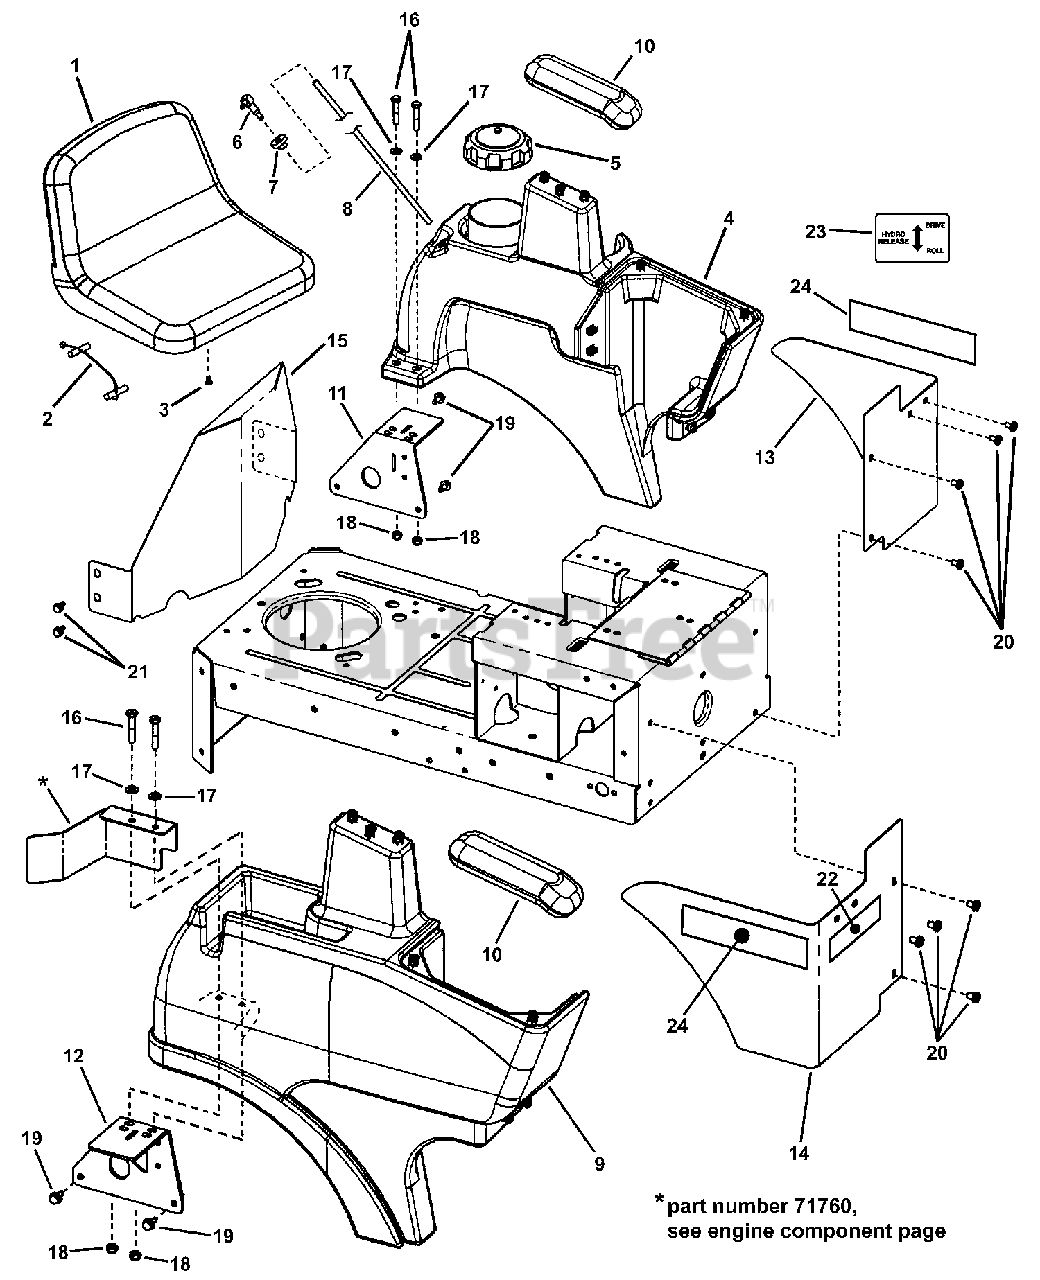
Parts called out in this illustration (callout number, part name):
1	SEAT, Milsco High Back
2	TETHER, Seat
3	SCREW, 1/4-20 x 5/8" Pan Head Self-Tap (Torx)
4	ASSEMBLY, Fuel Tank/L.H.Fender
5	GAS CAP w/Screw Vent
6	FITTING, Dapco
7	GROMMET
8	DIP TUBE
9	ASSEMBLY, R.H. Fender
10	ARM REST, HOZ
11	WELDMENT, Fuel Tank Support
12	WELDMENT, Fender Support
13	FENDER, L.H. Lower
14	FENDER, R.H. Lower
15	HEAT SHIELD, Engine
16	SCREW, 5/16-18 x 1-3/4" Hex Head Cap, GR 5
17	WASHER, .34 x .69 x .08 Flat
18	NUT, 5/16-18 Hex Nyloc
19	SCREW, 5/16-18 x 5/8" Hex Washer Self-Tap
20	SCREW, 5/16-18 x 1/2" Pan Head Self-Tap (Torx)
21	SCREW, 5/16-18 x 1/2" Hex Washer Self-Tap
22	DECAL, SCRAMBLER
23	DECAL, Hydro Release
24	DECAL, SNAPPER
